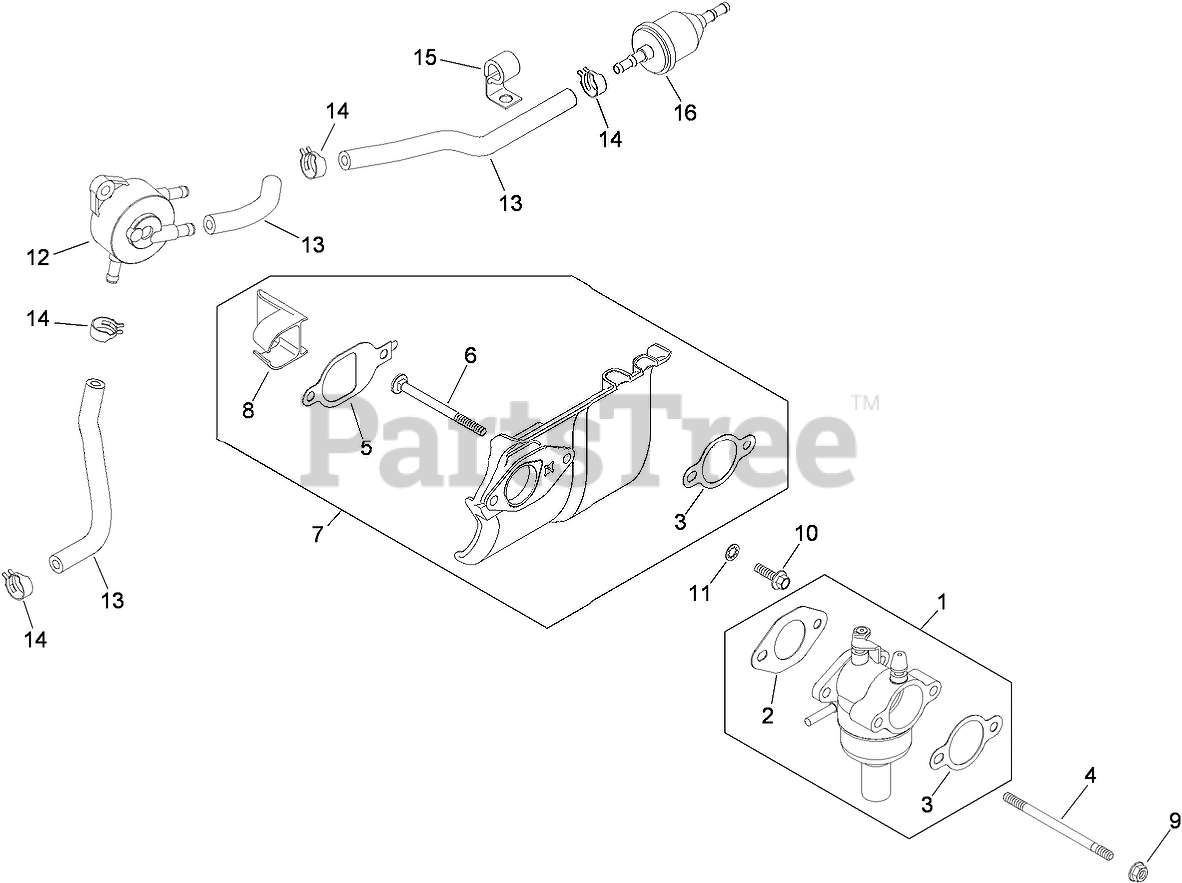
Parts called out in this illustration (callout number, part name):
1	CARBURETOR KIT (INCLUDES REF 2, 3)
2	Gasket-Carburetor
3	Gasket-Base, Air Cleaner
4	Stud-Mounting, Carburetor (M6X1.0X100)
5	GASKET-DEFLECTOR, HEAT
6	STUD-CARBURETOR
7	HEAT DEFLECTOR KIT (INCLUDES REF 3, 5, 6, 8)
8	INSERT-PORT, INTAKE
9	NUT-FLANGE (M6X1.0)
10	Screw-Flange, Hex (M6x1.0x20)
11	Washer-Lock, Internal Tooth (1/4)
12	PUMP-FUEL
13	LINE-FUEL (24.0 CUT TO LENGTH)
14	CLAMP-HOSE, SPRING (1/2)
15	CLIP-CABLE
16	FILTER-FUEL
